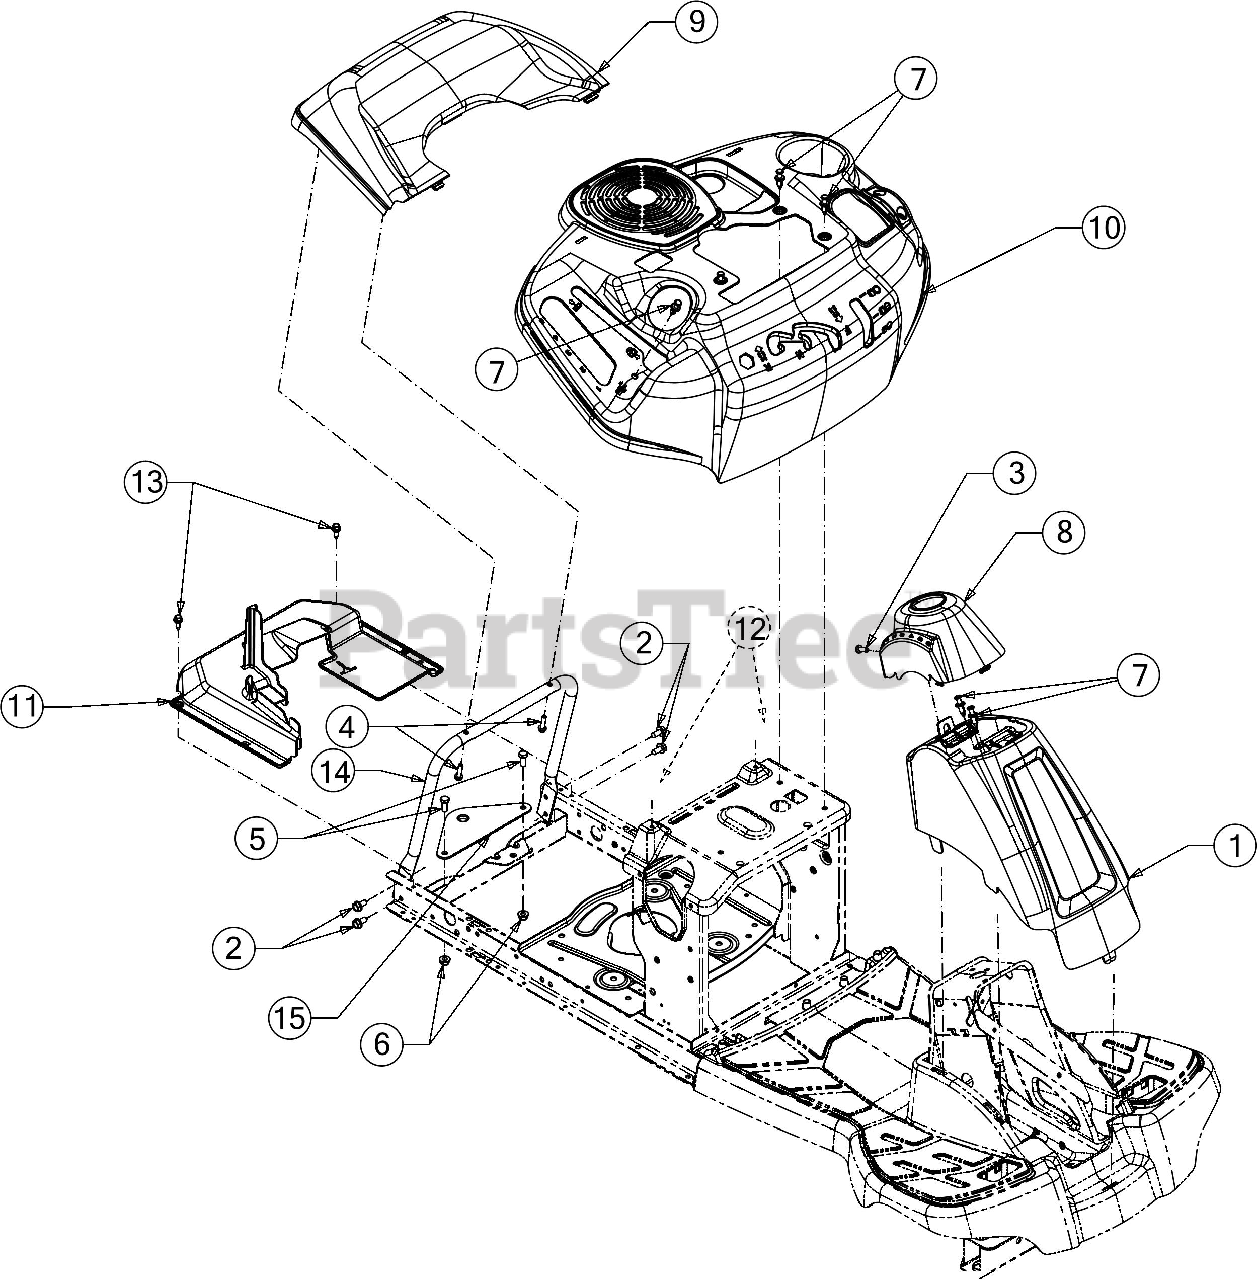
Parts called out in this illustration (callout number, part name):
1	COLUMN COVER ASSEMBLY (ORANGE)
2	SCREW 5/16-18 x .750
3	SCREW 1/4-20X.75
4	SCREW 1/4-15 x 1.00
5	SCREW 5/16-18 x .75 GR5
6	FLANGE LOCK NUT 5/16-18
7	PLASTIC RIVET
8	STEERING COLUMN CAP
9	REAR COVER
10	FENDER
11	DRIVE OVER REAR
12	BUMPER .62 DIA x .50
13	SHOULDER SCREW
14	REAR SUPPORT TUBE
15	HITCH PLATE
